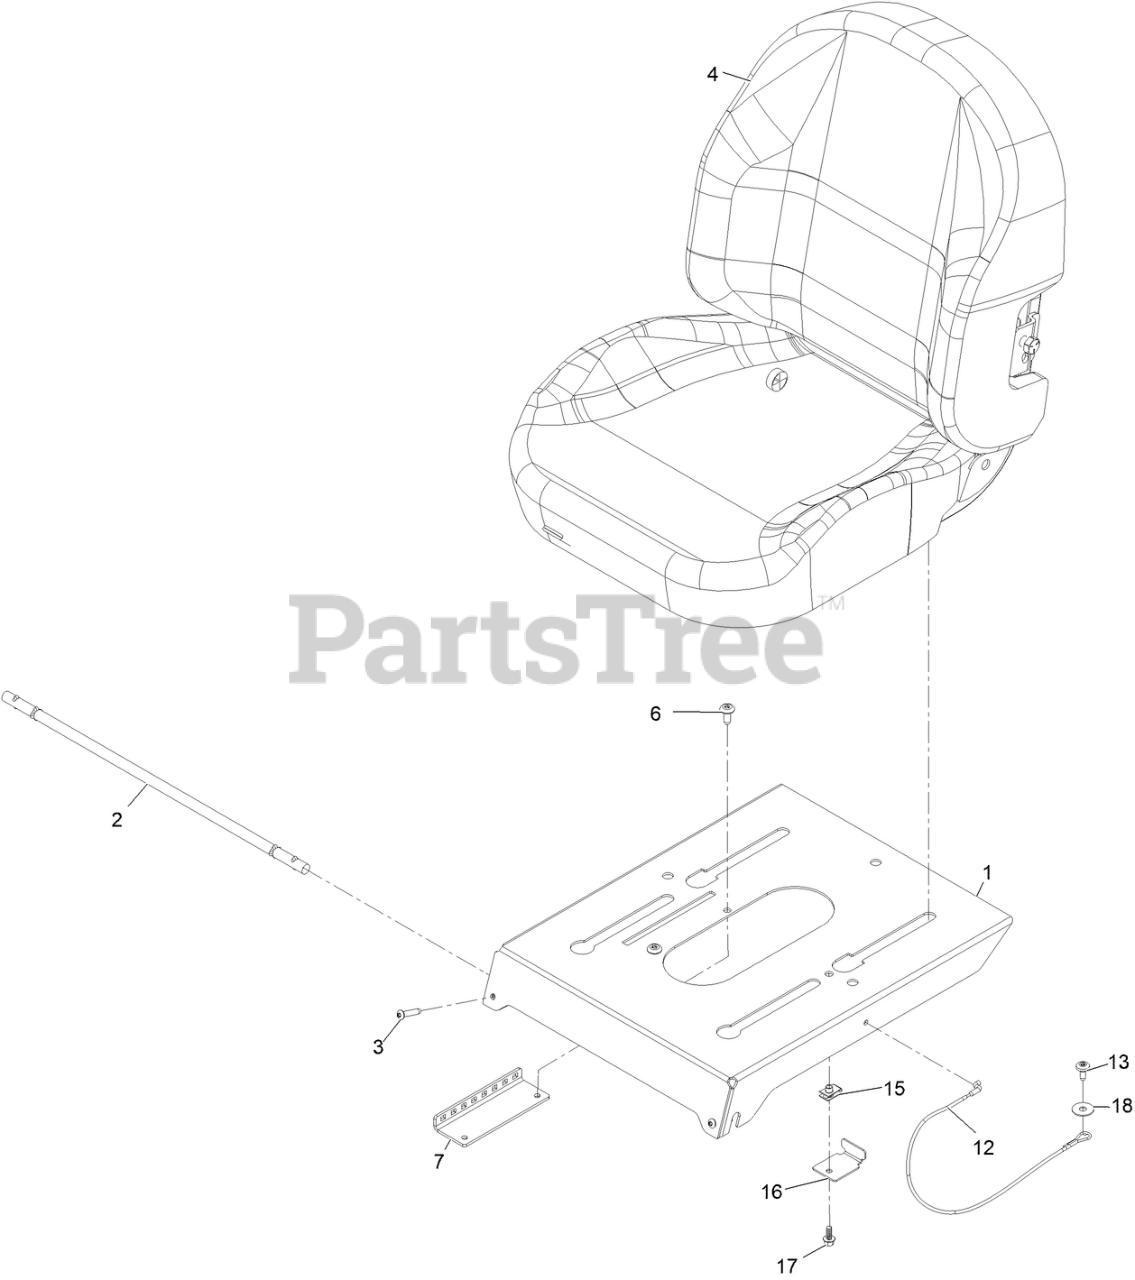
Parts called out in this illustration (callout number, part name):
2	ROD-PIVOT
3	SCREW-TTH, THREAD ROLLING
4	ASM-Seat Exmark
7	BRACKET-LATCH, SEAT
12	CABLE-LANYARD
13	SCREW-SHOULDER
16	Bracket-Stop, Seat
17	SCREW-HHF
18	Washer-Flat
